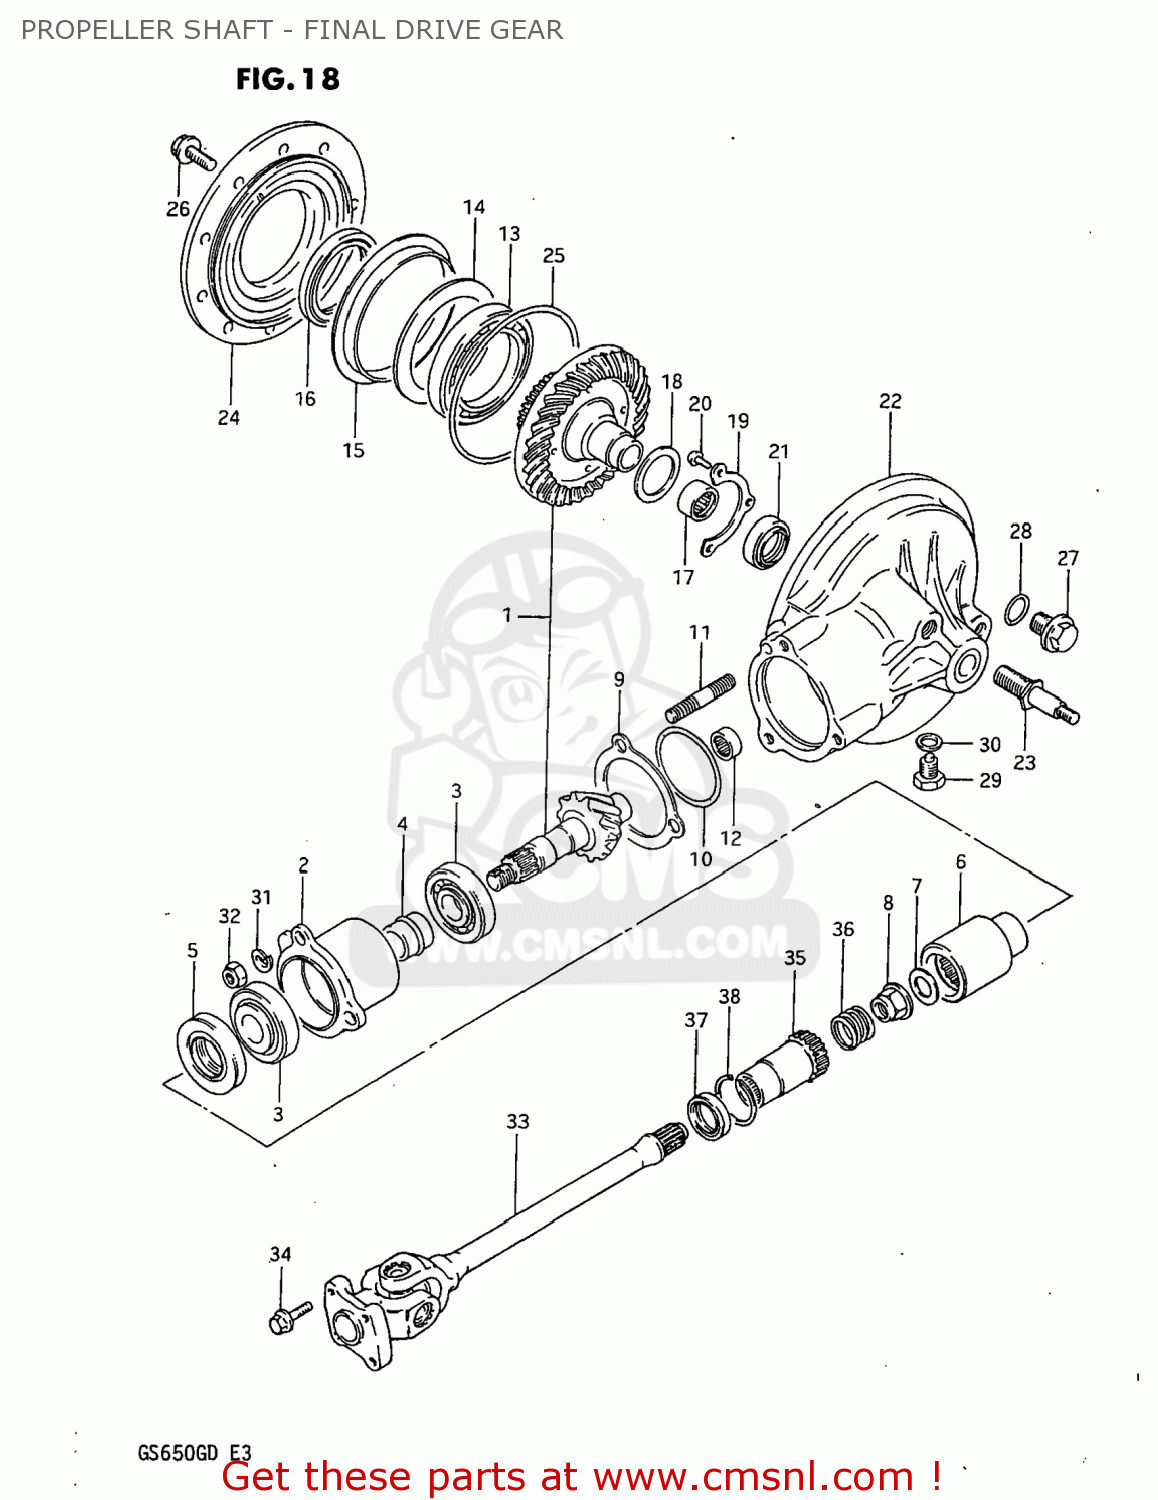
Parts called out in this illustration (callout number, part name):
1	GEAR SET,FINAL BEVEL (N
2	HOUSING,DRIVE GEAR
3	BEARING
4	SPACER
5	SEAL,OIL(32X54X7)
6	GEAR,FINAL DRIVE
7	WASHER(14X29X4)
8	NUT
9	SHIM,DRIVE GEAR HOUSING
10	O RING(D:2.4,ID:62.6)
11	STUD 10X30
12	BEARING
13	BEARING(70X110X13)
14	SHIM,DRIVEN GEAR BEARING T0.35
15	PLATE,FINAL DRIVEN BRG OIL
16	SEAL,OIL(70X96X16)
17	BEARING(32X46X17.7)
18	SHIM,FINAL DRIVEN GEAR
19	RETAINER,FINAL DRIVEN GEAR BRG
20	SCREW 6X12
21	SEAL,OIL(30X42X7)
22	CASE,FINAL GEAR
23	STUD
24	CASE,FINAL GEAR BEARING
25	O RING(D:3.5,ID:131.6)
26	BOLT
27	PLUG
28	O RING(D:2.4,ID:17.8)
29	PLUG
30	GASKET(14X19.2X2) (NAS)
31	LOCK WASHER
32	NUT
33	SHAFT ASSEMBLY,PROPELLER
34	BOLT(8X17)
35	COUPLING,PROPELLER SHAFT
36	SPRING
37	SEAL,OIL(30X40.5X5.5)
38	CIRCLIP
